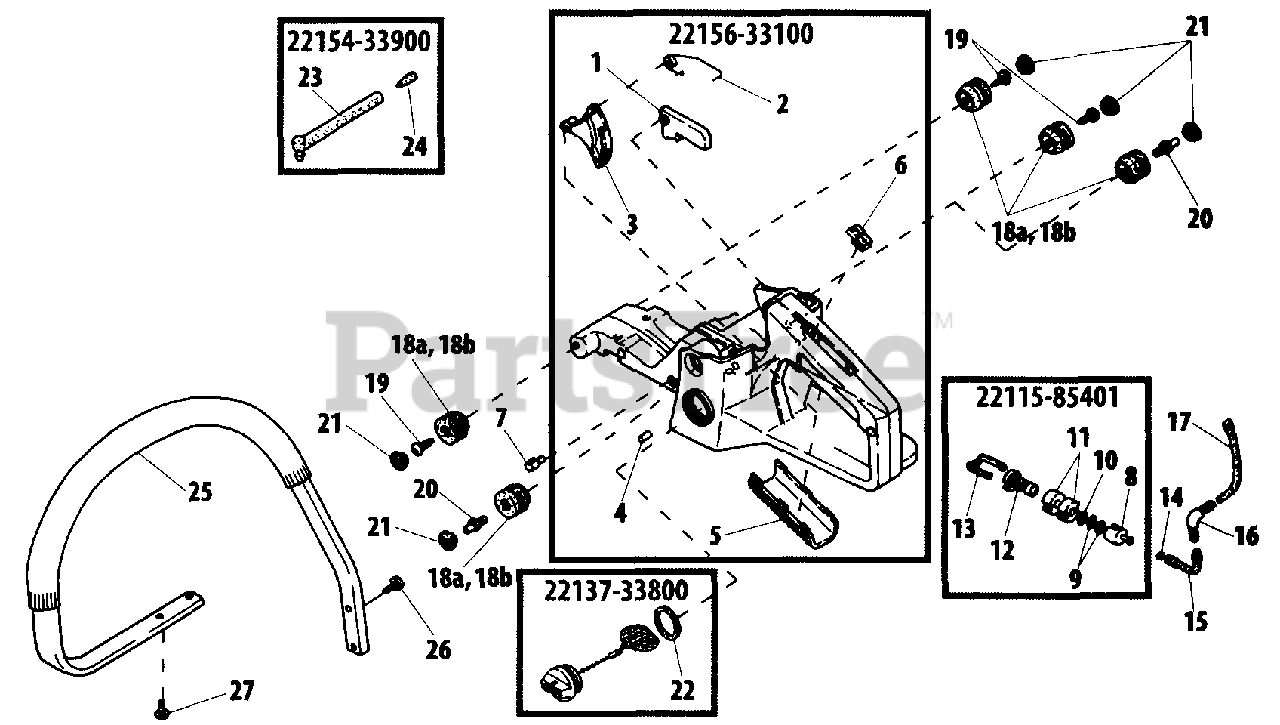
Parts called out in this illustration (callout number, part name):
1	LOCKOUT, THROTTLE
2	SPRING, LEVER
3	TRIGGER, THROTTLE
4	PIN 4×25
5	GRIP
6	STOPPER, SLIDE
7	SUPPORT
8	WEIGHT, FUEL LINE
9	SCREEN, FILTER
10	RING, RETAINING
11	FILTER, FUEL
12	BODY, FUEL FILTER
13	CLIP, FILTER
14	CLIP Ø6
15	PIPE, FUEL
16	CONNECTOR
17	PIPE, FUEL
18A	CUSHION
18B	CUSHION - HD
19	BOLT M5
20	BOLT M5
21	CAP, CUSHION
22	GASKET, CAP
23	PIPE, FUEL VENT
24	VENT ASSY
25	HANDLE, FRONT
26	BOLT 5×21
27	BOLT 5×17
22115-85401	FILTER, FUEL
22137-33800	CAP ASSY, FUEL
22154-33900	VENT ASSY
22156-33100	REAR HANDLE ASSY
